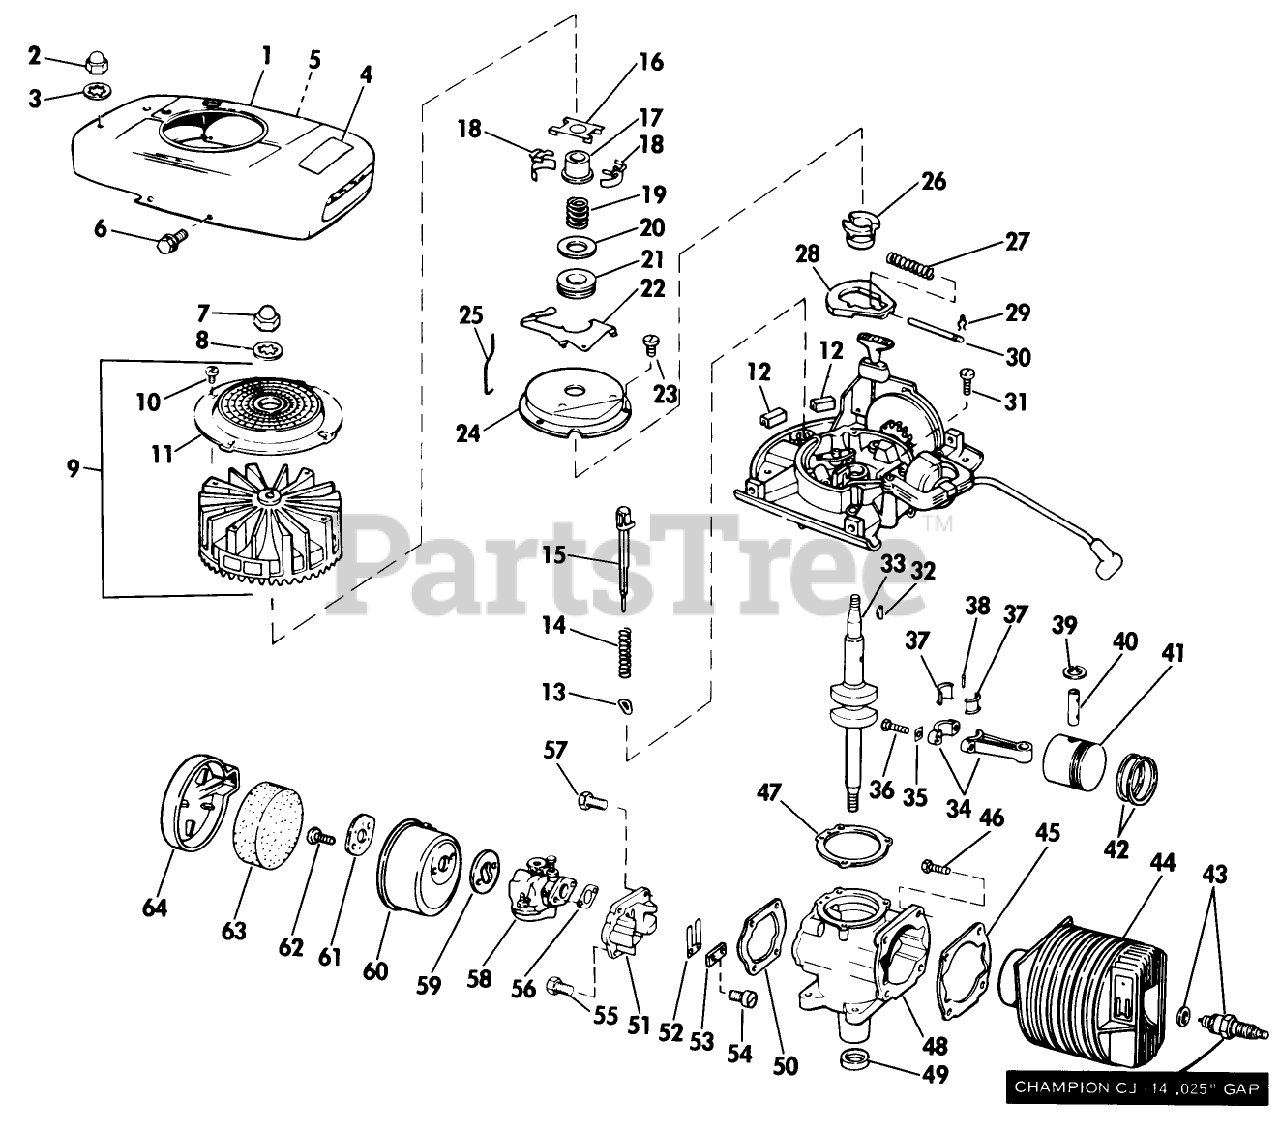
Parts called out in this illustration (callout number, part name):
2	PALNUT S
9	Flywheel Screen Assy.
10	SCREW F
14	SPRING S
17	COLLAR S
21	THRUST COLLAR S
22	LEVER-GOVERNOR S
23	SCREW S
24	DUST COVER S
26	SPARK ADV. S
27	SPARK ADV. SPRING S
28	FLYWEIGHT S
29	SPARK ADJ. SPRING
30	PIN,SPARK ADV. S
37	LINER ASM
39	RING-RETAINING
43	Spark Plug Gasket Champion CJ-14, .025" Gap
45	GASKET S
47	GASKET S
51	REED PLATE AY. S
53	PLATE-BACKUP, REED
55	SCREW S
56	GASKET S
57	SCREW S
59	GASKET S
62	SCREW S
63	AIR FIL.ELEM S
